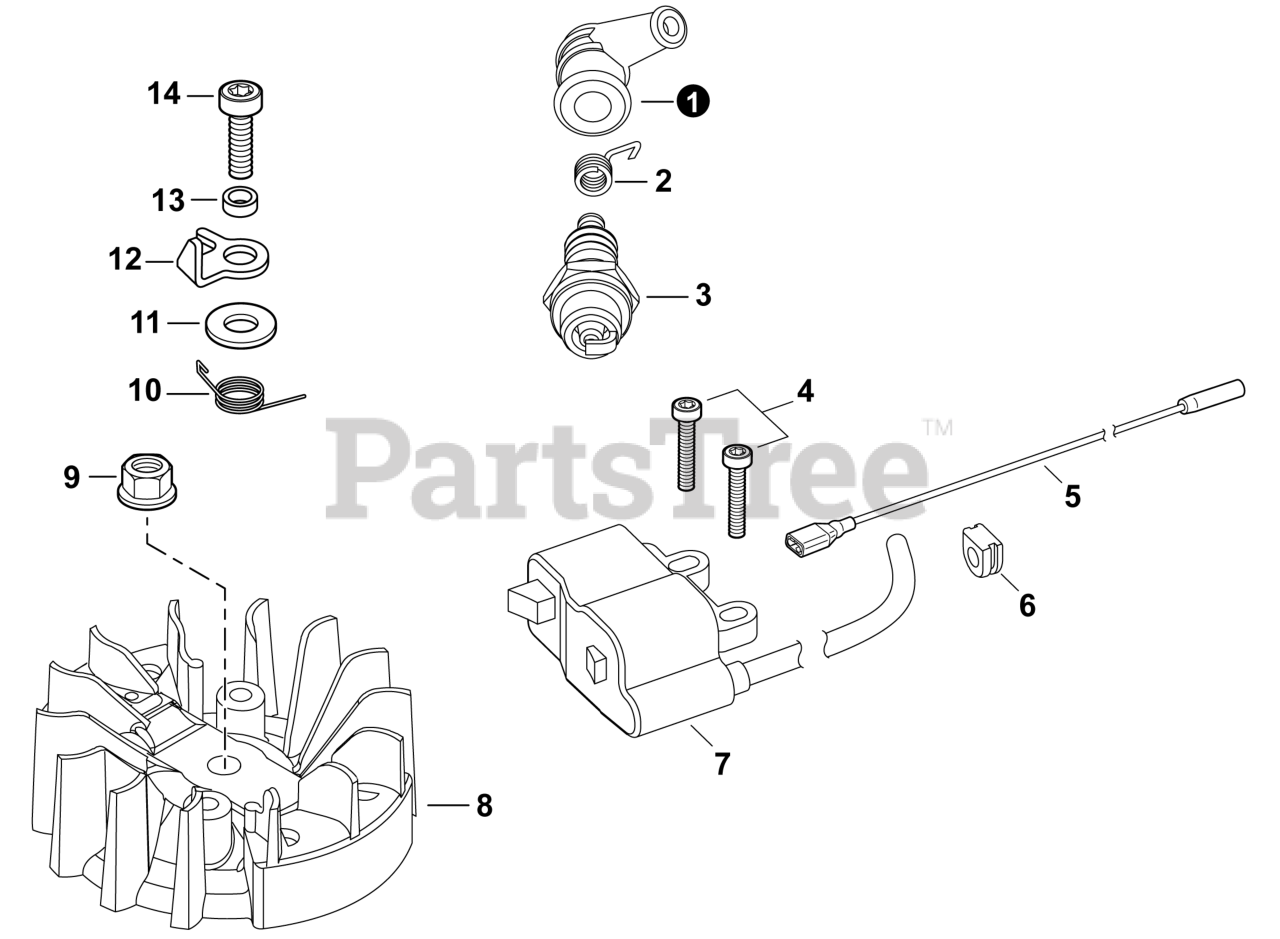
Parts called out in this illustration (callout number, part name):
1	CAP, SPARK PLUG
2	TERMINAL, SPARK PLUG
3	SPARK PLUG - BPMR8Y
4	BOLT, TORX 4×16
5	LEAD L= 85 MM
6	GROMMET
7	COIL, IGNITION
8	FLYWHEEL
9	NUT, FLANGE M6
10	SPRING, TORSION
11	WASHER 5.5×16×0.8
14	BOLT, TORX 5×16
